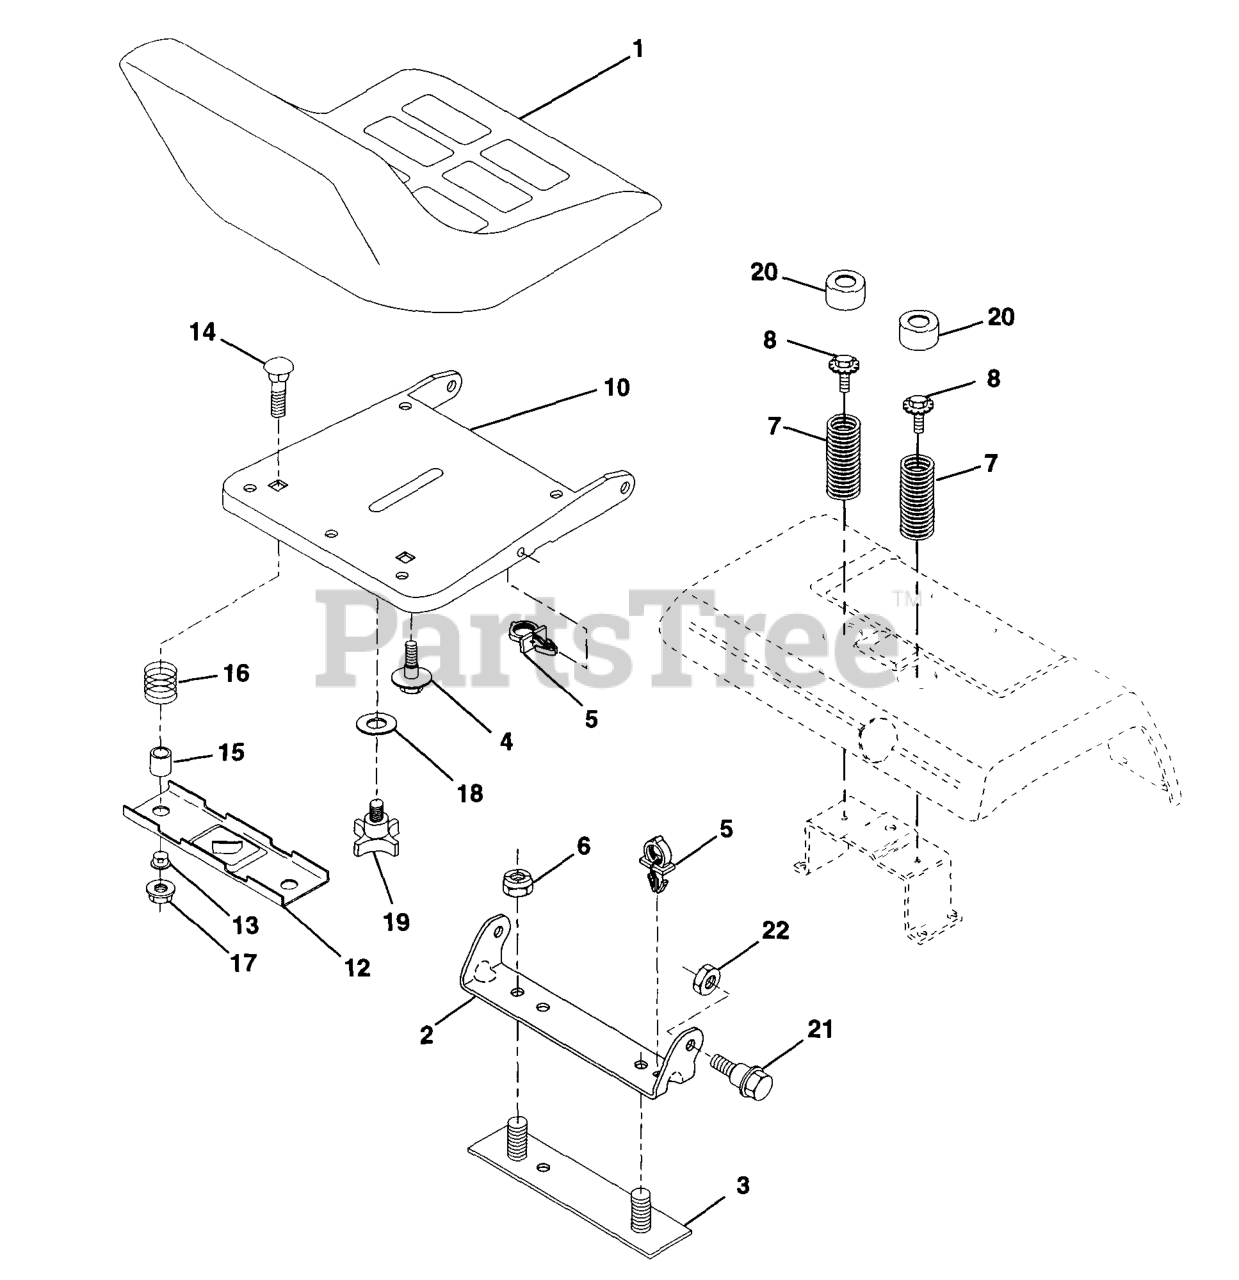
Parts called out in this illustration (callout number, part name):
1	SEAT
2	SEAT PIVOT BRKT
3	STRAP
4	BOLT,SHOULD
6	NUT
7	SPRING COMPRESSION
8	BOLT HEX WASHER HD 5/16-18
10	PAN, SEAT
12	BRKT SWITCH
14	Bolt, Carriage 1/4-20 X 1-3/8
15	SPACER SPLIT
16	SPRING COMPRESSED
17	NUT T
19	KNOB 1/2" YT
20	CAP SPRING
21	BOLT SHOULDER 5/16-18
22	LOCKNUT
